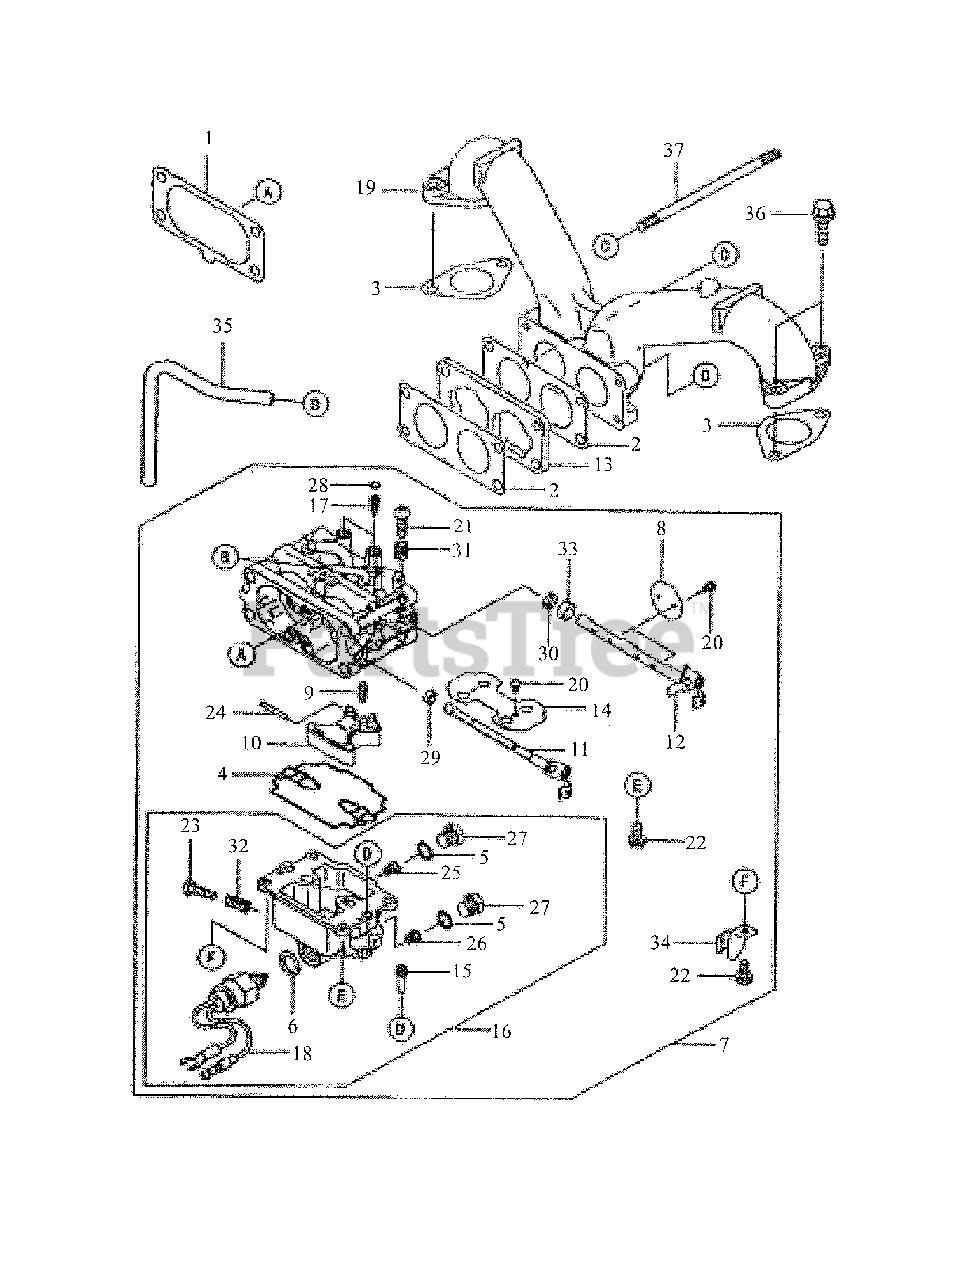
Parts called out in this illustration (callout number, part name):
1	Gasket, Air Filter
2	Gasket, Carburetor
4	Gasket,Float Chamber
5	Gasket,Main Plug
6	Gasket, Solenoid
7	Carburetor Assembly
8	Valve-Throttle
11	Shaft-Choke
12	Shaft-Throttle
16	Chamber-Float
19	Manifold, Intake
25	Jet-Main # 104
26	Jet-Main # 106
27	Plug,Main Jet
28	Plug, Expansion
35	Tube 4.76x7.94x160
36	Bolt-Flange
37	Bolt-Stud
